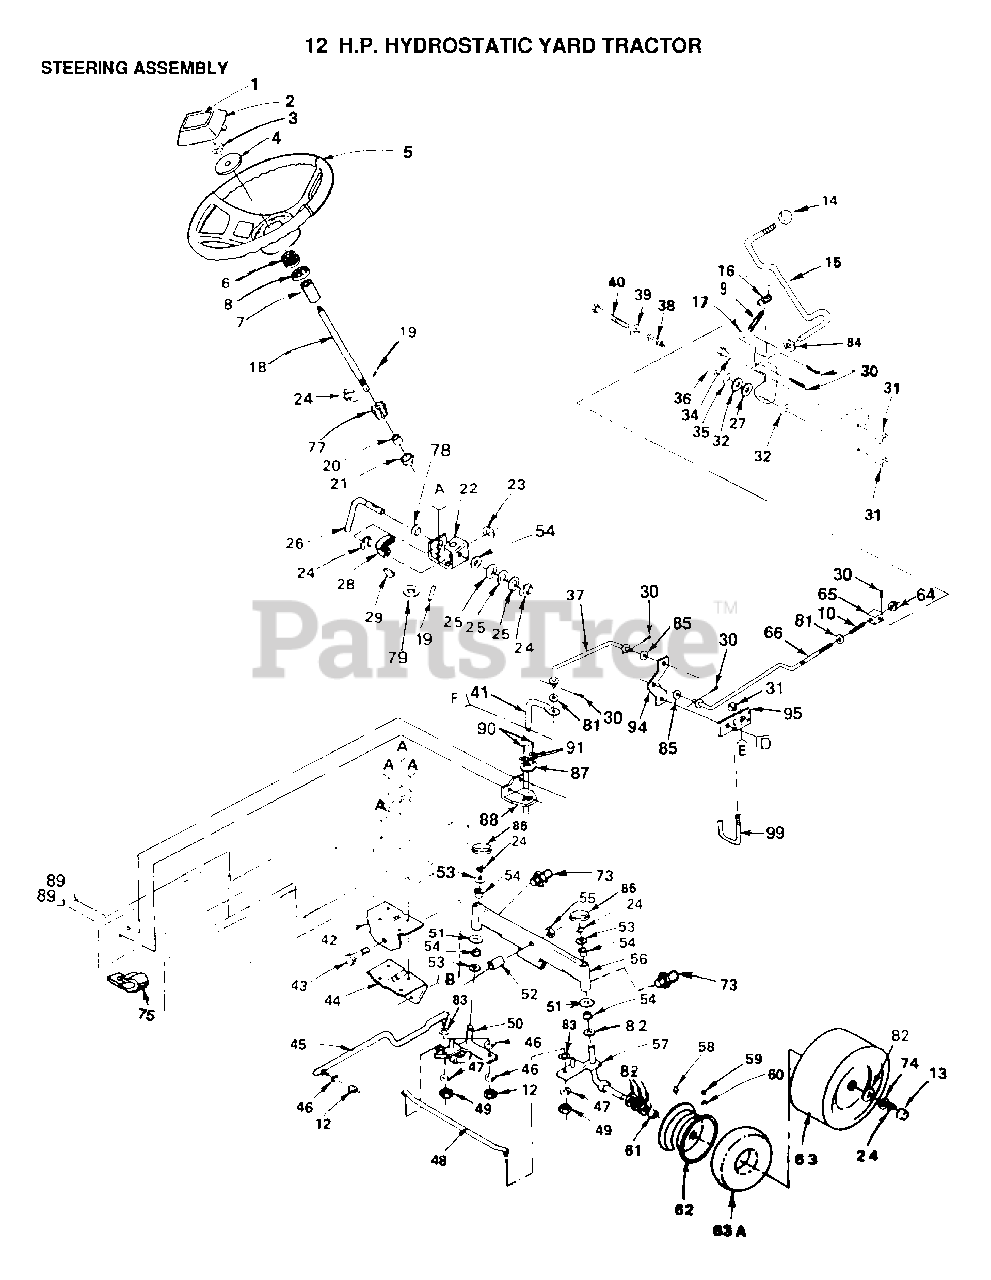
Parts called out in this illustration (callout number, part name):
1	DECAL, STEERING WHEEL INSERT
2	INSERT-WHEEL LT
4	WASHER
6	ADAPTER LT
9	SPRING.RETAINER
10	SPRING GTV
13	HUB CAP
14	KNOB.DUCKHEAD.1/2
15	ROD.YTH
16	SPRING TORSION
17	BRKT CONTROL HYT
18	STEERING SHAFT T
20	SHAFT SPACER LT
21	BUSHING
23	WASHER D
24	RING
25	WASHER .T
26	ROD STEERING T
28	GEAR.SECTOR.HYT
29	KEY-WOODRUFF LT
30	COTTER PIN
32	WASHER FRIC HYT
34	BOLT HYT
35	WASHER D
36	SPACER HYT
37	LINK CONTROL
38	SPRING HYT
39	WASHER
40	BOLT - HEX 3/8 - 16 X 3
41	ARM ASM PUMP
42	SUPPORT-SADDL T
43	BOLT LT
44	SUPPORT.SADDLE.FT
45	LINK-DRAG LT
46	LOCKWASHER
47	LOCKWASHER
48	ROD TIE
49	NUT.LOCK.5/16-24
50	SPINDLE-LH LT
51	WASHER
52	BEARING
53	WASHER .T
54	COL. SRTG. BEAR.
55	"NUT-LOC,FLANGE LT"
56	FRONT AXLE
58	FITTING LT
59	VALVE STEM LT
60	VALVE CAP
61	"FLANGE, BEARING"
65	TRUNION HYT
66	ROD ADJ CONTROL
73	ZERK M
74	WASHER
75	INSUL CLIP T
77	GEAR PINION T
78	NYLINER T
81	WASHER T
83	WASHER M
84	WASHER
85	WASHER T
86	CAP
87	GUIDE CONTROL
88	BRKT
89	SCREW
90	SCREW
91	WASHER
94	BELLCRANK
95	BRKT BELLCRANK
99	KEEPER
